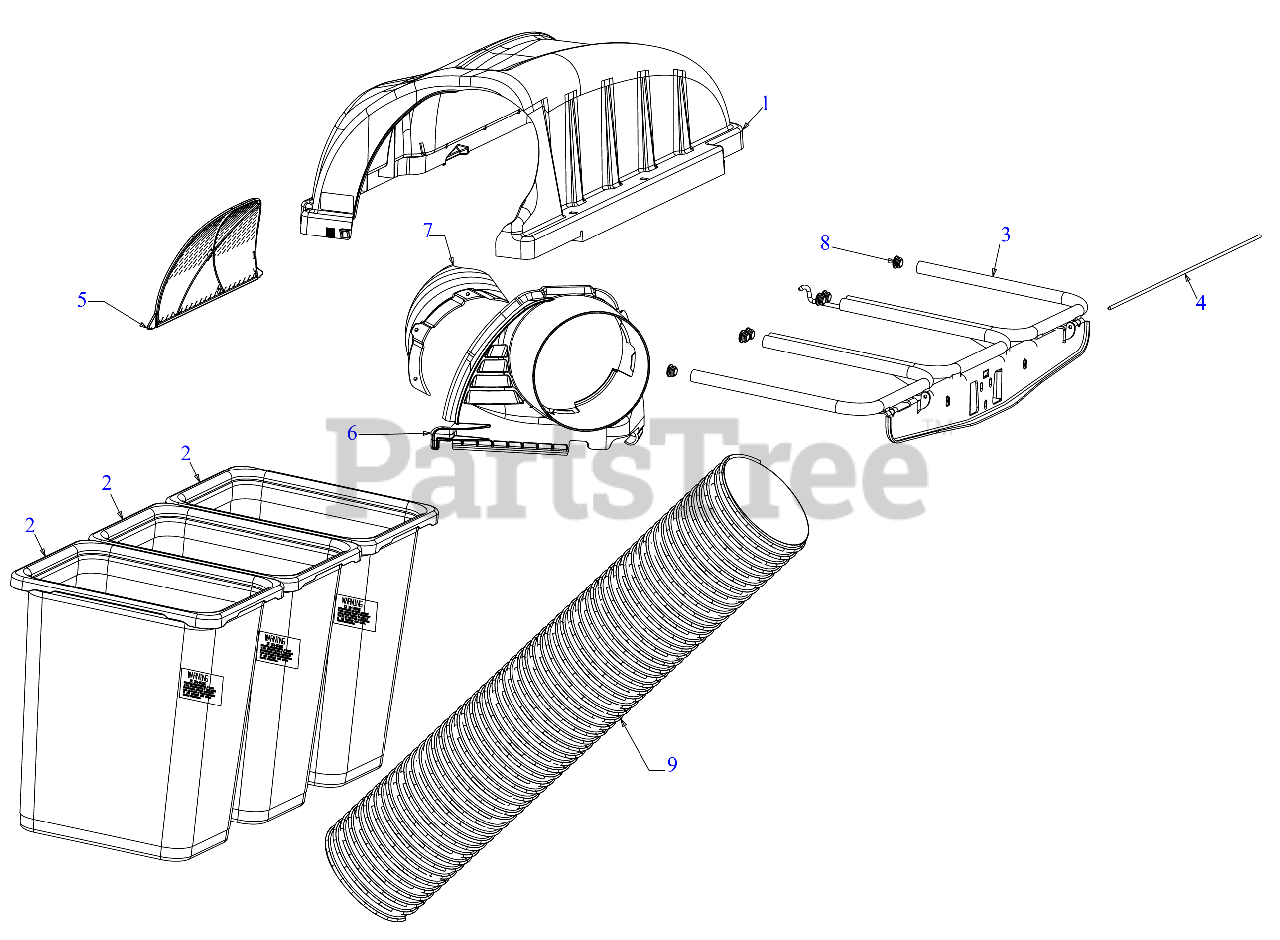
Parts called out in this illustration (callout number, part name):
1	TRIPLE BAGGER COVER
2	GRASSBAG ASSEMBLY W/ HARD BOTTOM
3	SUPPORT ASSEMBLY (POWDER BLACK)
5	BAGGER COVER SCREEN
6	UPPER CHUTE SUPPORT
7	BAGGER DEFLECTOR
9	9" BAGGER HOSE
